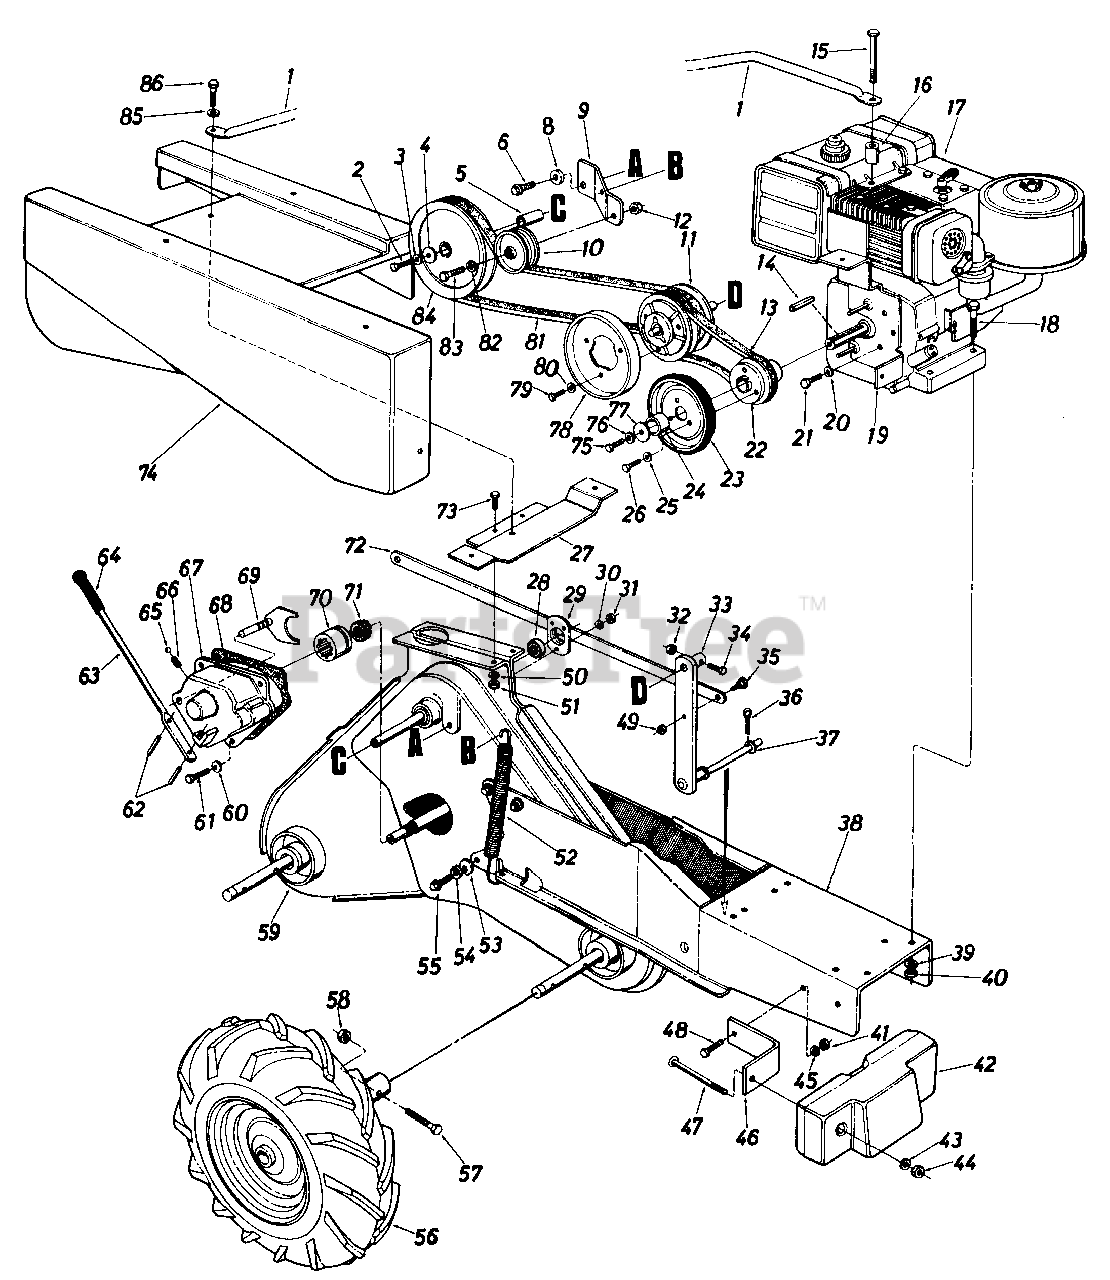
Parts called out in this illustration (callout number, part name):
1	Engine Brace
2	Hex L-Scr. 5/16-24 x .75" Lg.
3	L-Wash. 5/16" I.D.
4	Fl-Wash. 5/16" I.D.
5	Spacer .637" I.D. x .78" O.D. x 1.44" Lg.
6	Hex Self-Tap Scr. 3/8-16 x 1.25" Lg.
8	Shoulder Spacer
9	Idler Bracket
10	Fl-Idler 2.75" Dia.
11	Variable Speed Ass'y.
12	Hex Ins. L-Nut 3/8-16 Thd.
13	"V"-Belt 5/8" x 27.0" Lg.
14	Sq. Key 1/4" x 1.50" Lg.
15	Hex Bolt 5/16-18 x 4.00" Lg.
16	Spacer Engine Brace
17	Engine
18	Hex Bolt 5/16-18 x 1.75" Lg.
19	Belt Cover Support Ass'y.
20	L-Wash. 5/16" I.D.
21	Hex Bolt 5/16-24 x .62" Lg.
22	Engine Pulley Ass'y.
23	Friction Wheel Ass'y.
25	L-Wash. 5/16" I.D.
26	Hex Bolt 5/16-18 x .50" Lg.
27	Belt Cover Mounting Brkt.
28	Ball Bearing
29	Bearing Housing 1-3/8" O.D.
30	L-Wash. 1/4" I.D.
31	Hex Nut 1/4-28 Thd.
32	Hex Ins. L-Nut 1/4-20 Thd.
33	Variable Speed Brkt. Ass'y.
34	Hex Bolt 1/4-20 x 1.25" Lg.
35	Shld. Bolt 1/2" Dia. x .25" Lg.
36	Cotter Pin 1/8" Dia. x .75" Lg.
37	Fl-Wash. .686" I.D. x 1.25" O.D.
38	Frame Ass'y.
39	L-Wash. 5/16" I.D.
40	Hex Nut 5/16-18 Thd.
41	Hex Cent. L-Nut 3/8-24 Thd.
43	Fl-Wash. .50" I.D. x 1.0" O.D.
44	Hex Nut 1/2-13 Thd.
45	L-Wash. 3/8" I.D.
46	Weight Mtg. Brkt.
47	Hex Bolt 1/2-13 x 4.50" Lg.
48	Hex Bolt 3/8-24 x 1.00" Lg.
49	Hex Ins. L-Nut 3/8-16 Thd.
50	L-Wash. 1/4" I.D.
51	Hex Cent. L-Nut 1/4-28 Thd.
52	Spring Idler Bracket
53	Belleville Wash. 3/8" I.D.
54	L-Wash. 3/8" I.D.
55	Hex Self-Tap Scr. 3/8-16 x .75" Lg.
56	Wheel Ass'y. Comp. - R.H.
57	Hex Bolt 3/8-24 x 1.25" Lg.
58	Hex Ins. L-Nut 3/8-24 Thd.
59	Chain Case Ass'y. Comp.
60	L-Wash. 5/16" I.D.
61	Hex Tap Tite 5/16-18 x .75" Lg.
62	Headed Spiral Pin 3/16 x 13/16" Lg.
63	Engagement Lever
65	Ball Detent .250" Dia.
66	Compression Spring
67	Shift Housing - R.H.
68	Gasket - Shift Housing
69	Shift Yoke Ass'y. - R.H.
70	Clutch Dog
71	Clutch Dog Driver
72	Control Brkt.
73	Hex Bolt 1/4-28 x .62" Lg.
74	Shroud Belt Cover
75	Hex Bolt 3/8-24 x 1.00" Lg.
76	L-Wash. 3/8" I.D.
77	Fl-Wash. 3/8" I.D. x 1.12" O.D.
78	Friction Disc
79	Hex Bolt 1/4-28 x .50" Lg.
80	L-Wash. 1/4" I.D.
81	"V"-Belt 5/8" x 51" Lg.
82	L-Wash. 3 1/2" I.D.
83	Hex Bolt 3/8" x 1.50" Lg.
84	Input Pulley - Chain Case
85	Fl-Wash. 1/4" I.D.
86	Hex Wash. Hd. Self-Tap. 5/16 x .62" Lg.
